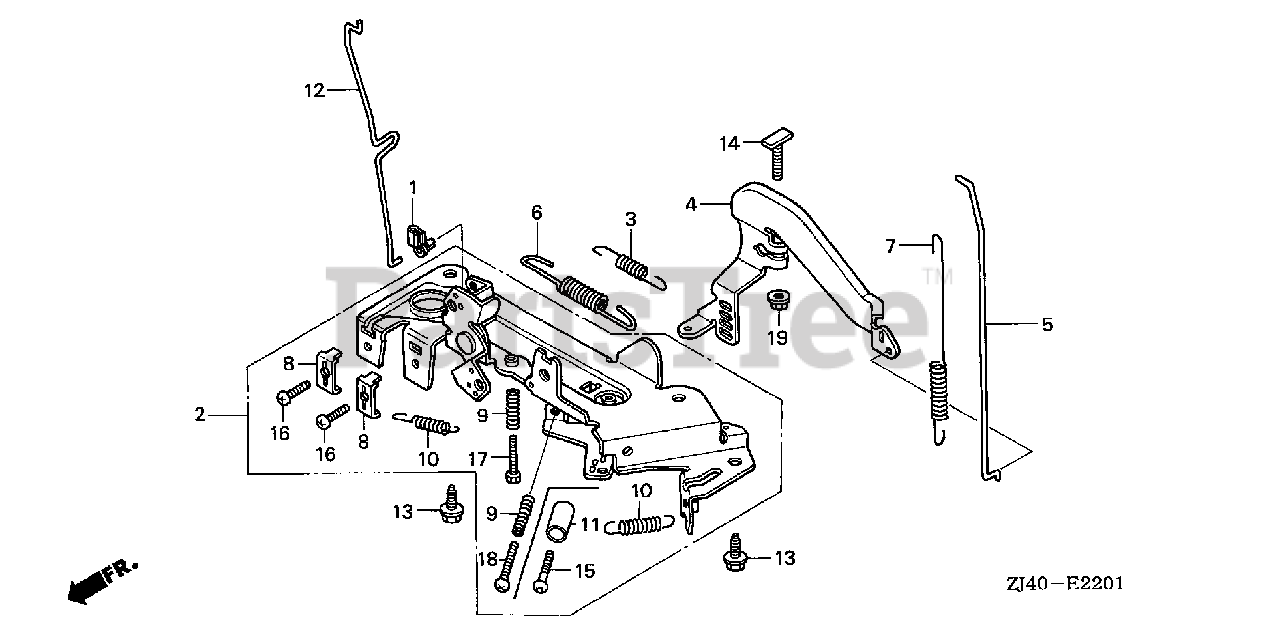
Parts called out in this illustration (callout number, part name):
1	JOINT, ROD
2	CONTROL ASSY.
3	SPRING, STARTER
4	ARM, GOVERNOR
5	ROD, GOVERNOR
6	SPRING, GOVERNOR
7	SPRING, THROTTLE RETURN
8	HOLDER, CABLE
9	SPRING, CONTROL ADJUSTING
10	SPRING, CABLE RETURN
11	COLLAR, STOPPER
12	ROD, CHOKE CONTROL
13	BOLT, FLANGE (6X14)
14	BOLT, GOVERNOR ARM
15	SCREW, RECESSED (5X28) (BLACK)
16	BOLT, SLOT (5X16)
17	BOLT, SLOT (5X25)
19	NUT, FLANGE (6MM)
